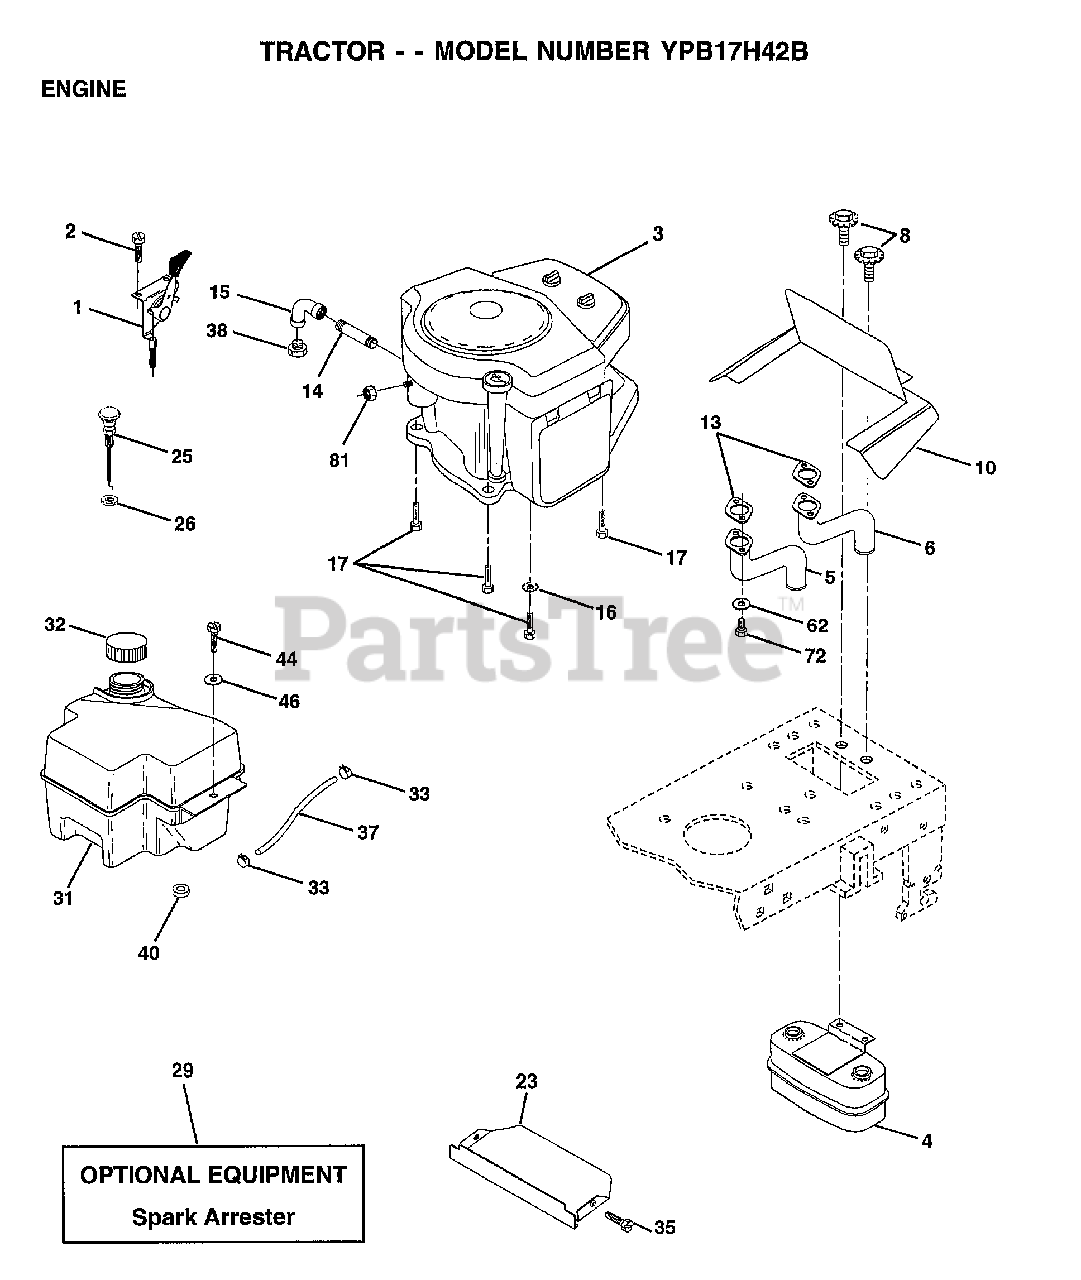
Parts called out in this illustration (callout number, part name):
1	CONTROL THROT. LH
2	SCREW LT
4	MUFFLER.TW.LOTONE
5	TUBE MANIFOLD LH
6	TUBE MANIFOLD RH
8	BOLT.5/16-18.UNC
10	SHIELD.BROWNING
14	PIPE NIPPLE LT
15	ELBOW
16	LOCKWASHER
17	SCREW LT
23	SHIELD BRN/DBR GUARD
25	CONTROL.CHOKE.37
26	"NUT,KEPS 3/8-24IM"
31	TANK.FUEL.FRONT.
32	CAP ASM FUEL
33	HOSE CLAMP
35	SCREW
37	LINE FUEL
44	SCREW HEX CRT
46	WASHER
62	LOCKWASHER
72	SCREW
81	NUT
